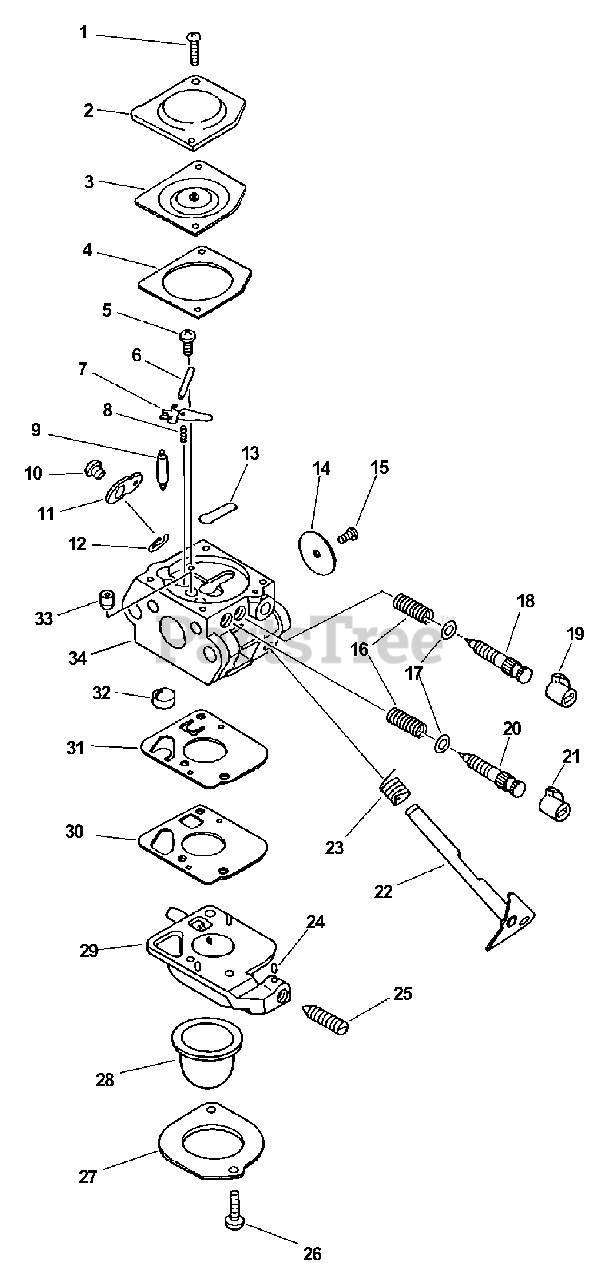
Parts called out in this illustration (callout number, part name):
2	COVER, METERING
3	DIAPHRAGM, METERING
4	GASKET, DIAPHRAGM
5	SCREW, METERING LEVER PIN
6	PIN, METERING LEVER
7	LEVER, METERING
8	SPRING, METERING LEVER
9	VALVE, INLET NEEDLE
10	RING, RETAINING
12	LEVER, THROTTLE
13	PLUG, WELCH
14	VALVE, THROTTLE
18	NEEDLE - LOW SPEED
19	CAP, LIMITER
20	NEEDLE - HIGH SPEED
21	CAP, LIMITER
22	SHAFT, THROTTLE
23	SPRING, TRIGGER
24	PIECE, FRICTION
25	SCREW, IDLE ADJUST
26	SCREW, RETAINER
27	RETAINER, PURGE BULB
28	BULB, PURGE
29	BASE, PURGE
30	GASKET, PUMP
31	DIAPHRAGM, PUMP
32	STRAINER
33	NOZZLE, CHECK VALVE
34	BODY, CARBURETOR
